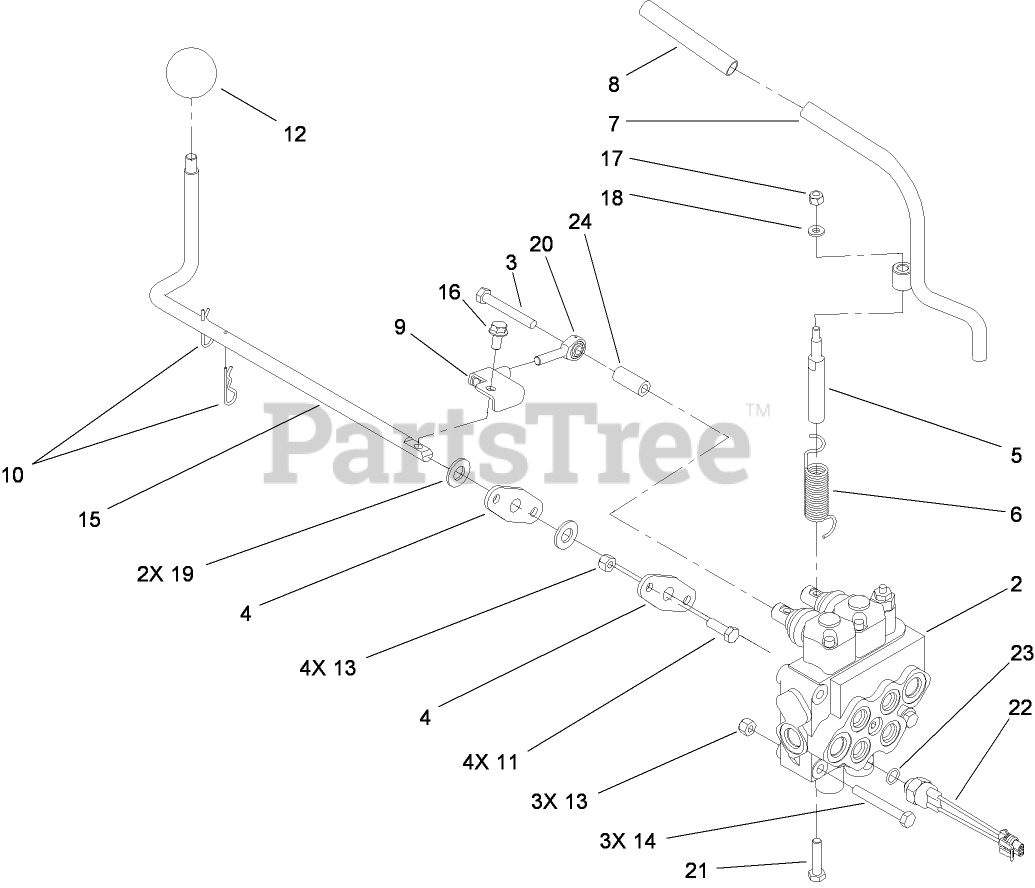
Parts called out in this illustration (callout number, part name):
2	HYD VALVE ASM
3	SCREW-HH
4	BEARING-WHEEL, FRICTION
5	SPACER-HIFLO
6	SPRING-TORSION
7	LEVER-AUXILIARY
8	GRIP-RUBBER
9	CONTROL ASM
10	PIN-HAIR
11	SCREW-HH
13	NUT-LOCK, NI
14	SCREW-HH
15	ROD-LEVER, CYLINDER
16	SCREW-HHF
17	NUT-LOCK, NI
18	WASHER-FLAT
19	WASHER-FLAT
20	BEARING-ROD END
21	SCREW
22	SWITCH-BALL
23	O-RING
24	SPACER
